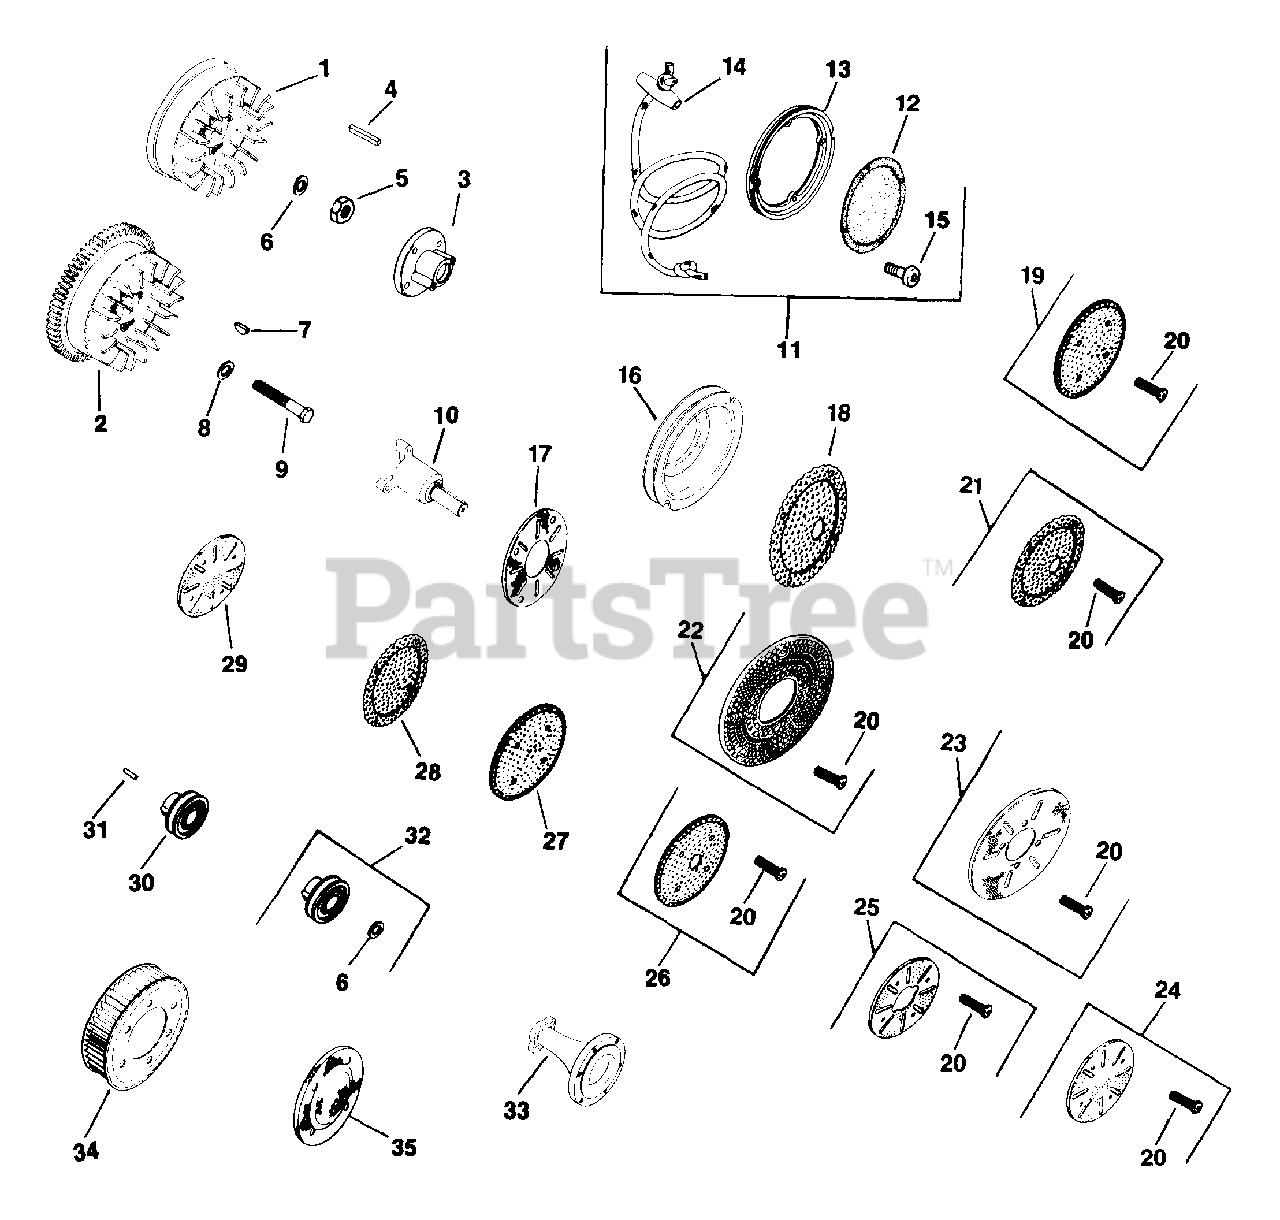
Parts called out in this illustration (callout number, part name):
2	FLYWHEEL - DISCONTINUED
4	KEY
5	NUT, 5/8 GRADE 2 - DISCONTINUED
6	WASHER - DISCONTINUED
7	KEY, 3/16" X 1"
8	WASHER (KM)-USE 12 468 03-S
9	SCREW, MACH 3/8-24X1-1/4"
12	SCREEN, GRASS
14	ROPE-DISCONTINUED
20	SCREW, POZ TRS HD 1/4-20X5/8" - DISCONTINUED
